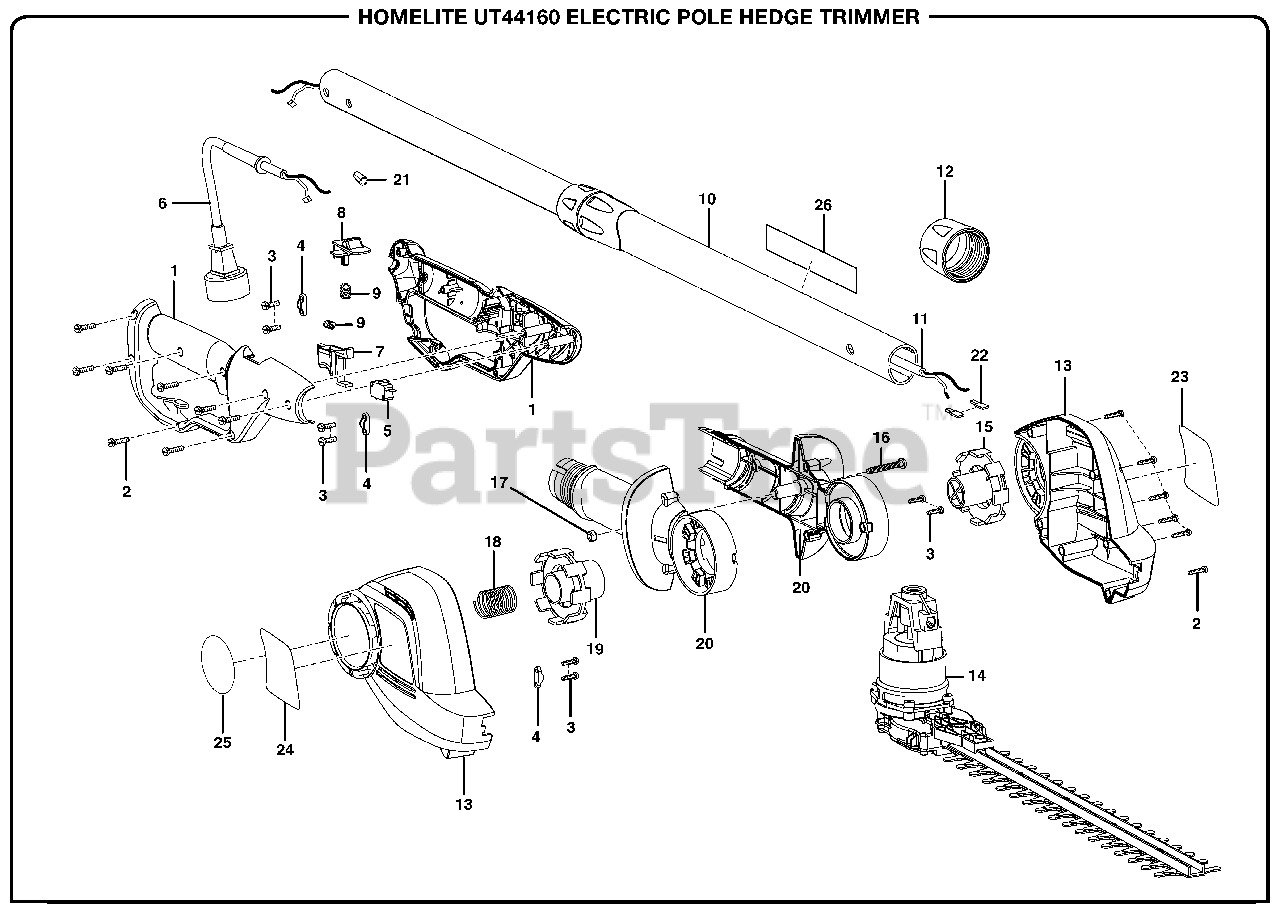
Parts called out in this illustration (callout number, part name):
1	Handle Assembly
2	Screw
3	Screw
4	Cord Clamp
6	Power Cord
7	Switch Trigger
8	Lock Off Button
9	Compression Spring
10	Pole Assembly
11	Spring Cord Assembly
13	Motor Housing Assembly
14	Motor w/Blade Assembly
15	Left Pivot Button
16	Bolt
17	Lock Nut
18	Compression Spring
19	Right Pivot Button
20	Pole Housing Assembly
22	Terminal
23	Data Label
24	Logo Label
25	Pivot Label
26	Warning Label
